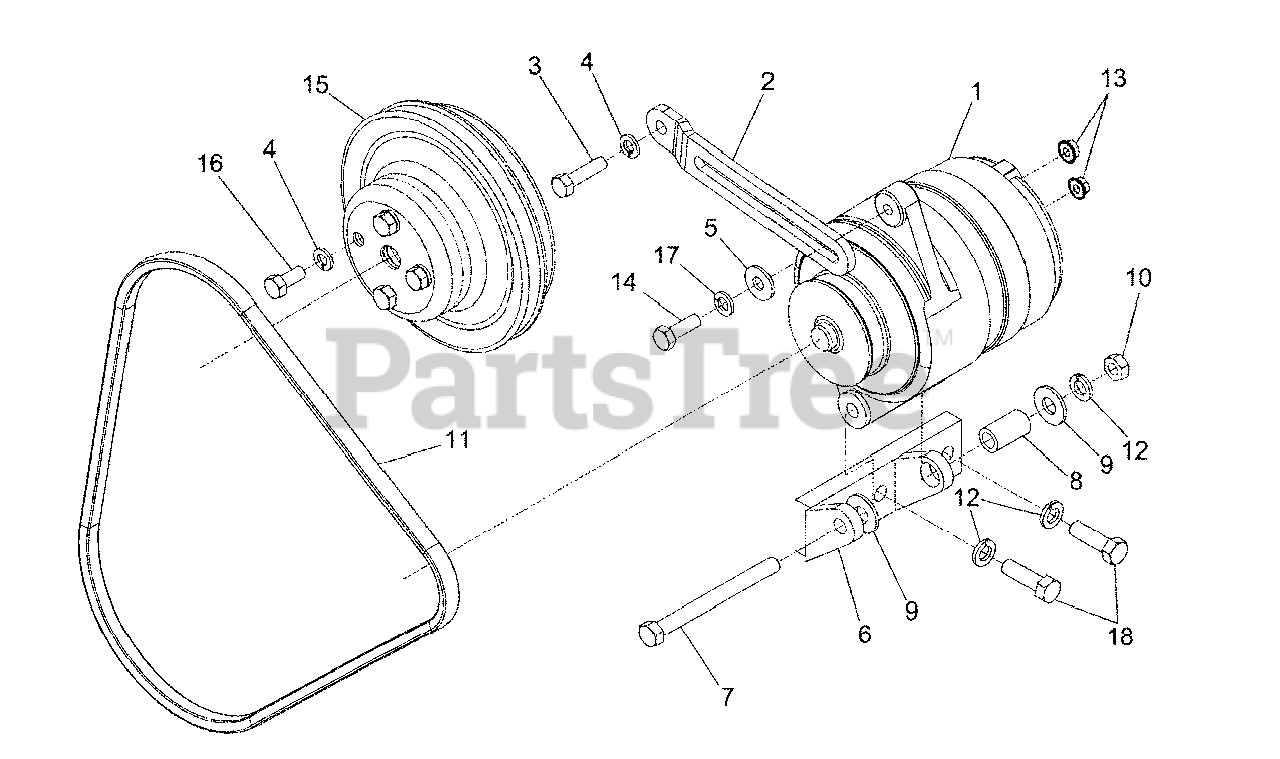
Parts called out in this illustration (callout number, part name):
2	BRACKET-ALTERNATOR
3	BOLT
4	WASHER-LOCK
5	WASHER-FLAT
6	BRACKET-ALTERNATOR
7	BOLT
8	SPACER
9	WASHER-FLAT
10	NUT
11	BELT-ALTERNATOR
12	WASHER
13	NUT
14	BOLT
15	PULLEY
16	BOLT
17	WASHER-LOCK
18	BOLT
